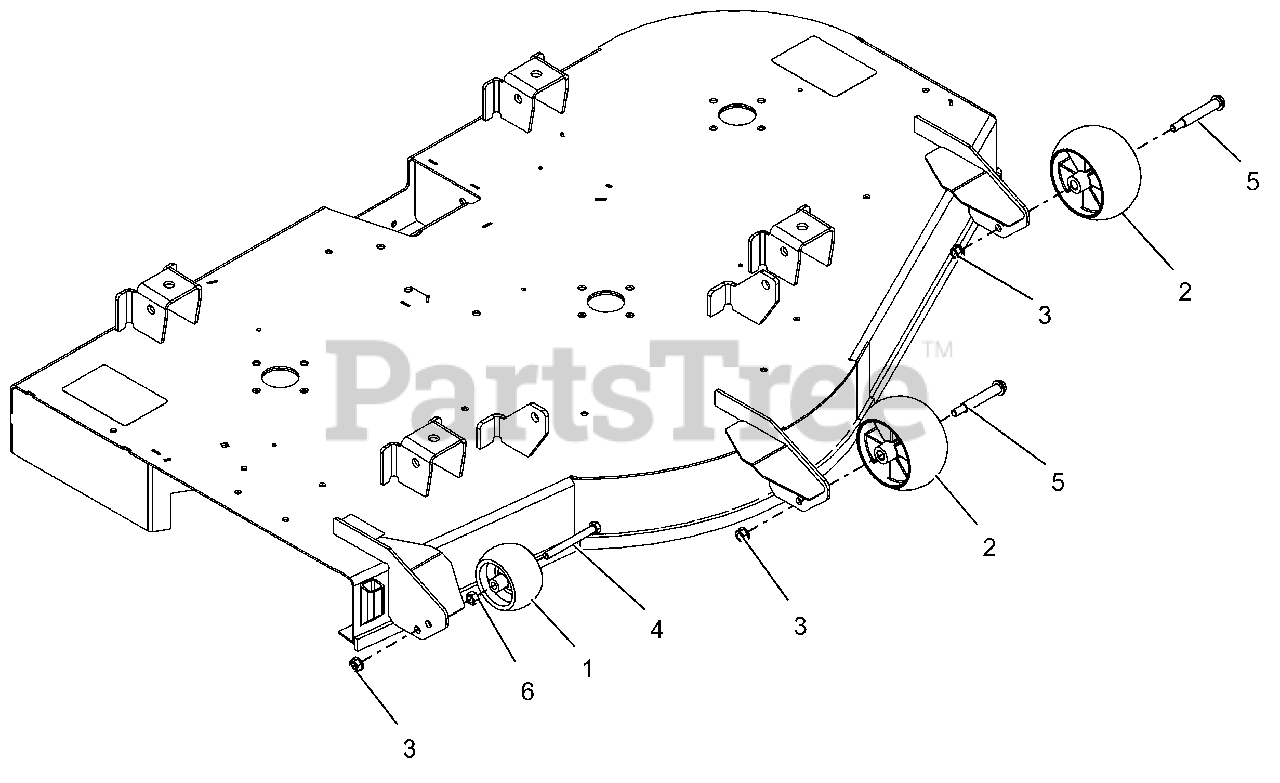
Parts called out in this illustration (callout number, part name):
2	ANTI-SCALP WHEEL - 5X OS
3	NUT-LK-CTR-FLG .375-16 GF ZCC
4	BLT, HEX .38-16X3.50 G5 ZCC
5	BLT-SHLDR .38-16X2.50 HWH G5
6	NUT-STD .375-16 G2 ZCC
